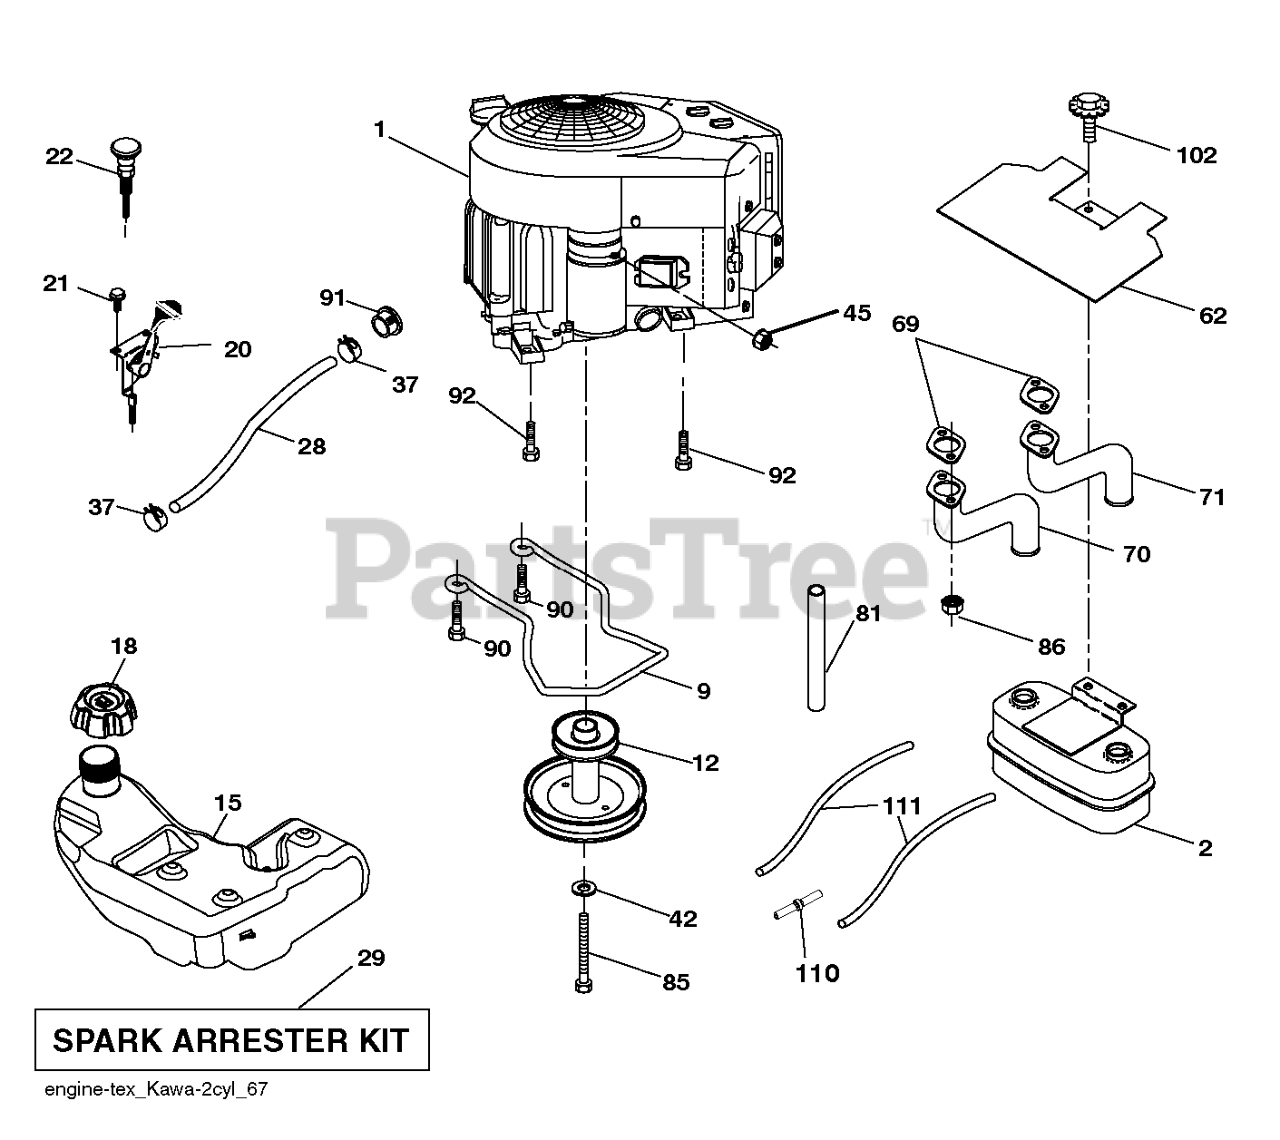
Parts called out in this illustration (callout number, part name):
2	MUFFLER.ASM.TWIN.MNTG.BRACKET
9	KEEPER.BELT.ENG.4.25"2.BLT.431
12	PULLEY.ENGINE
15	TANK.ASM.FUEL.3GA.CARB.17
18	FUEL CAP
18	CAP ASSY FUEL 3" GRAY
20	CONTROL.THROTTLE.COBRA.BLACK
21	SCREW.#10 X 0.750.BOS
22	CONTROL, CHOKE
28	HOSE 1/4" LOW PERMEATION FUEL
29	KIT.SPARK ARRESTOR 794945 B&S
37	HOSE CLAMP
42	WASHER 7/16 LOCK
45	NUT
62	SHIELD.HEAT.MUFFLER
69	GASKET.EXHAUST.KOHLER
70	TUBE.EXHAUST.RH.FR961/FR730
71	TUBE.EXHAUST.LH.FR961/FR730
81	TUBE, DRAIN OIL ASM.
85	BOLT.HEX.7/16-20X4.GR5.1.5BLUE
86	BLADE ADAPTER
90	SCREW 3/8-16X1
91	BUSHING.1.375OD
92	SCREW 3/8-16X1
102	SCREW
110	VALVE.ASM.ANTI-SLOSH
111	RP PURGE LINE
